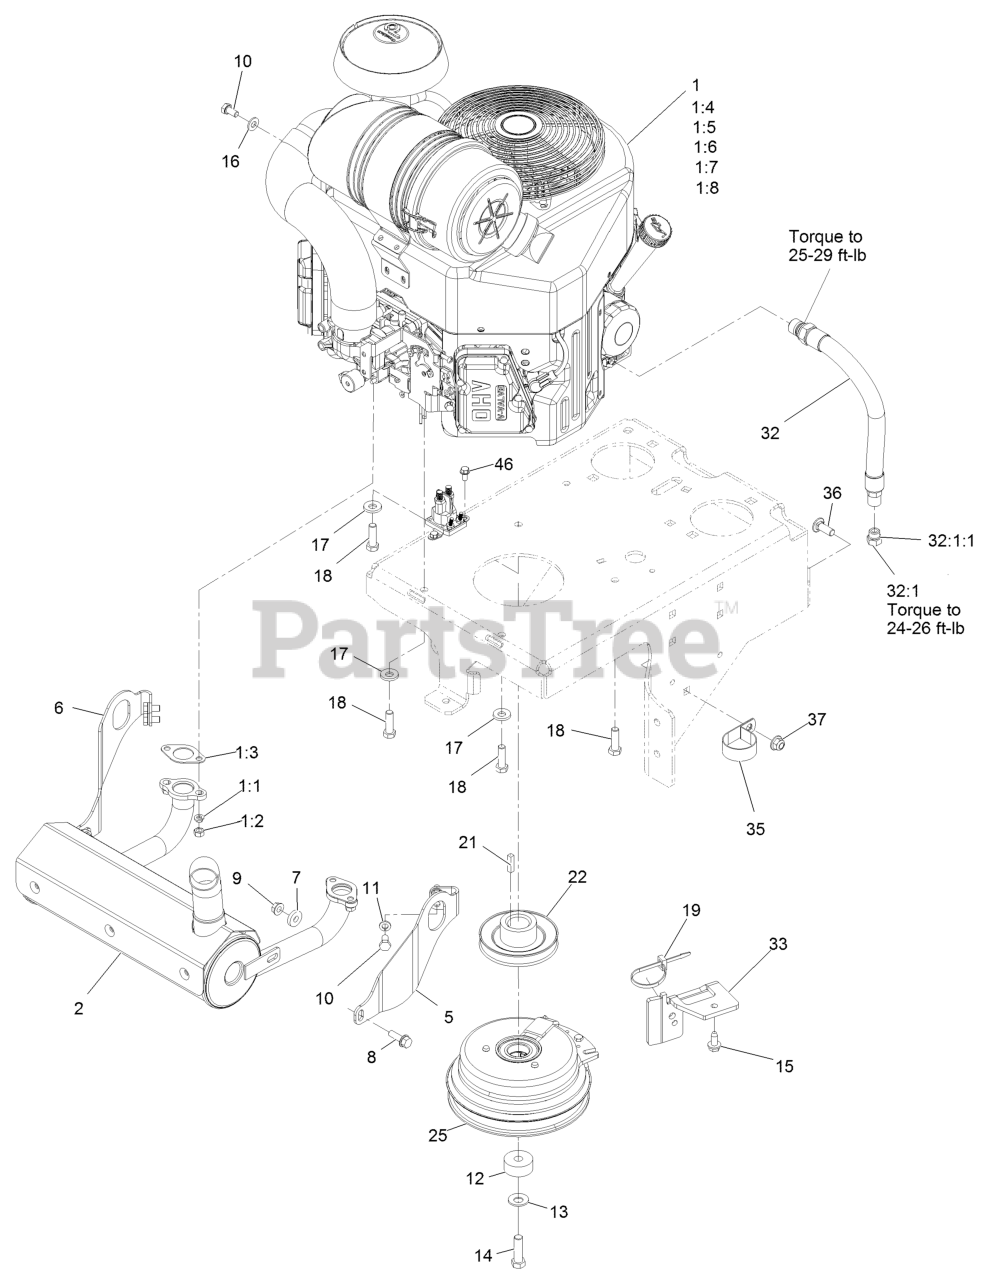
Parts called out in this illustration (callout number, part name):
1:1	Washer-Lock
1:3	Gasket-Exhaust
1:4	Filter-Oil
1:5	Spark Plug
1:6	Element-Filter, Air (Outer)
1:7	Element-Filter, Air (Inner)
1:8	Filter-Fuel
2	Muffler, Kawasaki, 22-26
5	Bracket-Muffler Mount, LH
6	Bracket-Muffler Mount, RH
8	Screw-HH Flg 5/16-18 X 1
9	Nut-Hex 5/16-18 Side Lock
10	Screw-HH M8-1.25 X 16Mm
11	Washer-Lock 5/16
12	Keeper-Clutch
13	Washer-Spring Disc 7/16
14	Screw-HH 7/16-20 X 1 1/2
15	Screw-HWH 5/16-18 X 3/4 Tf
17	Washer-Spring Disc 3/8
18	Screw-HH 3/8-16 X 1 1/4
19	Tie-Cable
21	Key-Machine 1/4 X 1/4 X 1
25	Clutch-200 Ft-Lb, 1.125 Bore - No D Driv
32	Asm-Hose Oil Drain W/Plug
32:1	Plug-W/O-Ring
32:1:1	O-Ring
33	Bracket-Anchor, Clutch
36	Bolt-Carriage 3/8-16 X 1
37	Nut-Nyloc 3/8-16 Flg
46	Screw-HWH 1/4-20 X 1/2 Taptite
